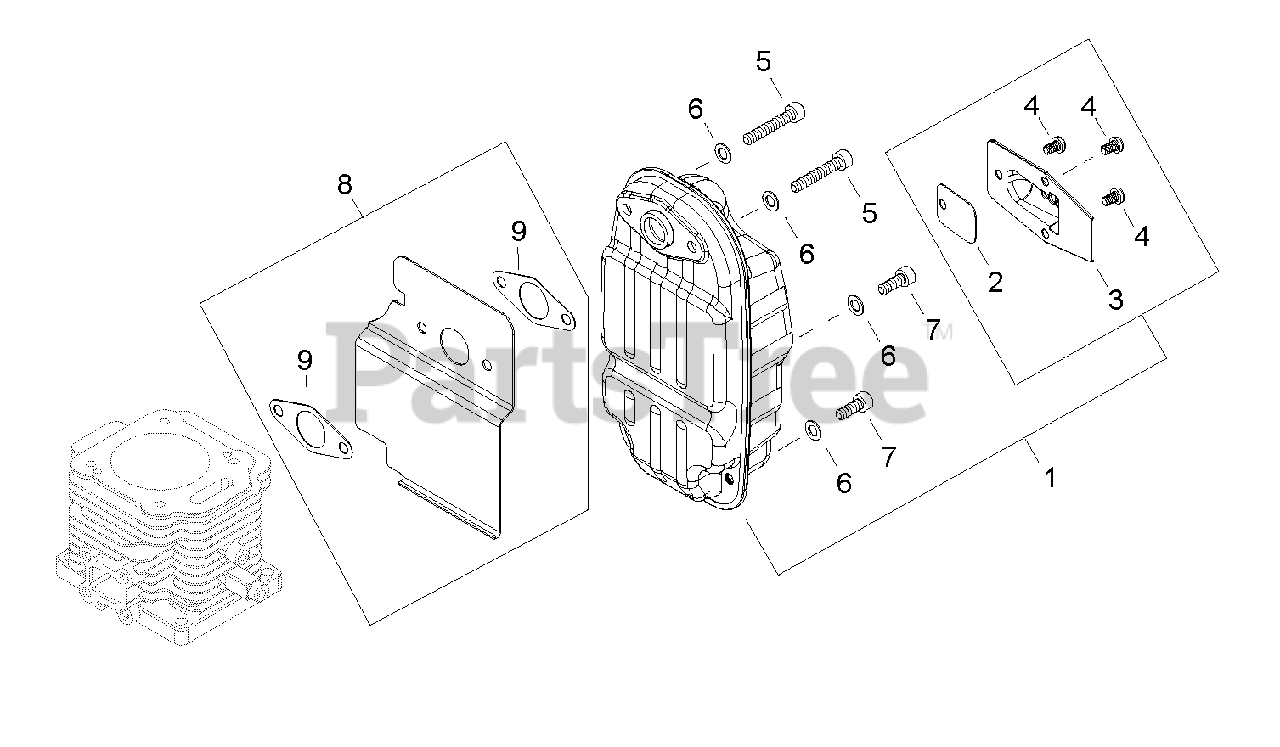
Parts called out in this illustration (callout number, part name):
1	MUFFLER ASSY
2	SCREEN, SPARK ARRESTOR
3	TAIL PLATE
4	SCREW - 5X8
5	SCREW - 6X35
6	WASHER - 6
8	GASKET
9	GASKET
